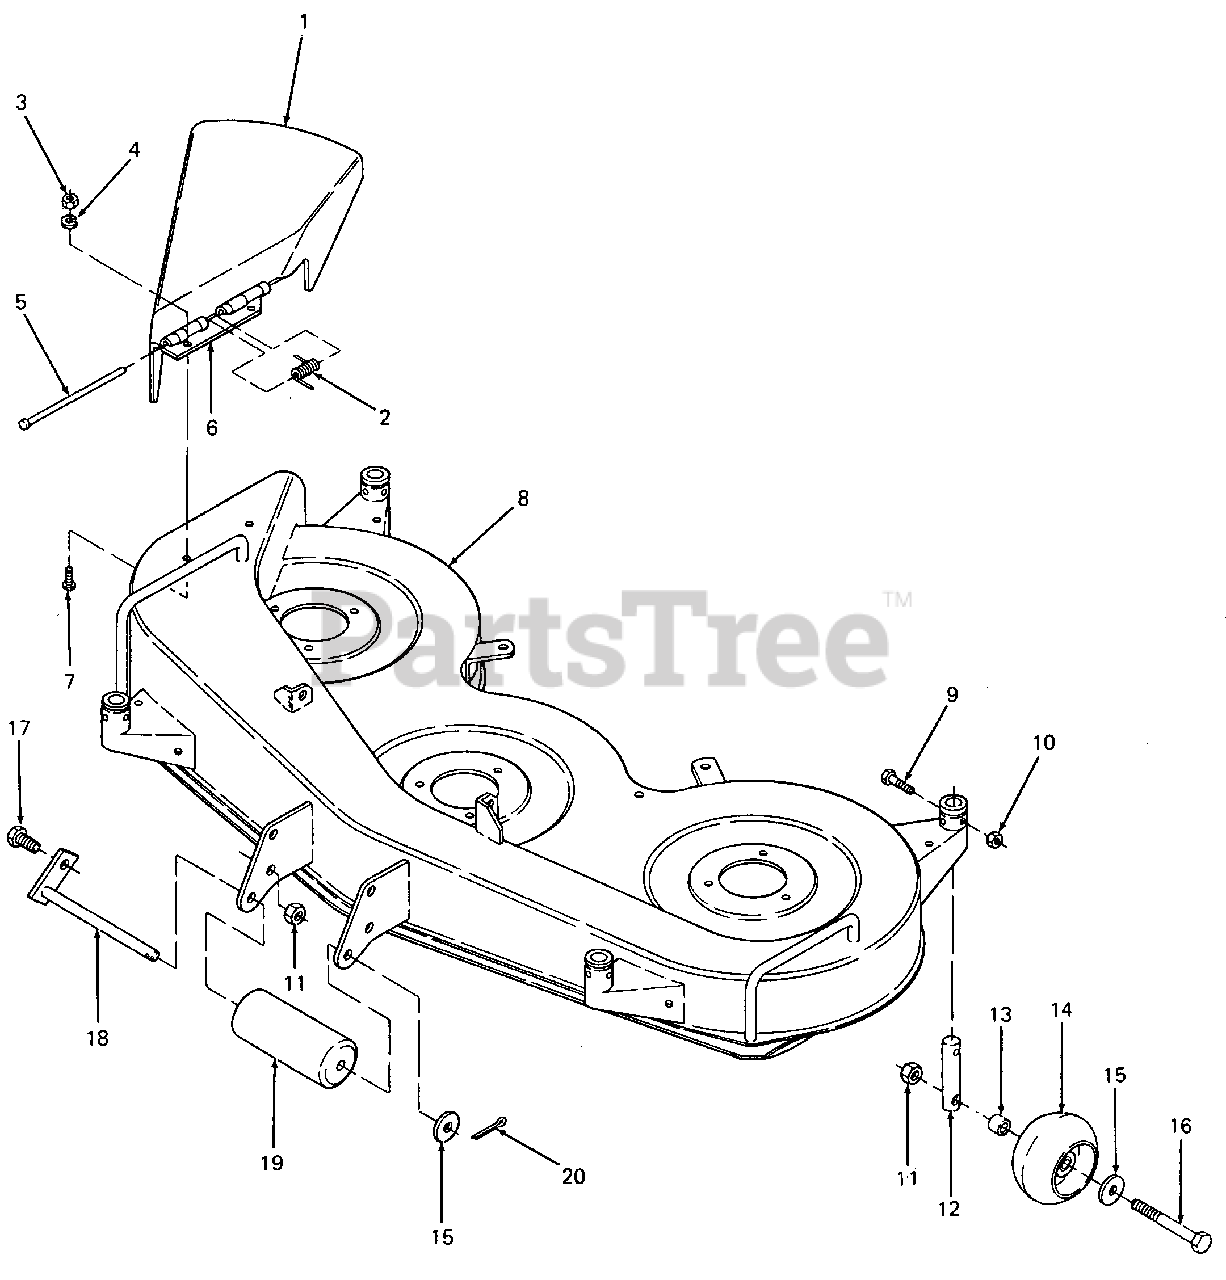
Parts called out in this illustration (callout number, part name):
1	Chute, Discharge w/Graphic
2	Spring, Torsion, .29 ID X 1.14 Lg
3	Nut, Hex Jam, 1/4-20
4	Washer, Lock, 1/4
5	Pin, Hinge, .25 Dia X 6.75 Lg
6	Hinge, Discharge Chute
7	Screw, Truss Mach, 1/4-20 X .75 Lg
8	Deck Assy w/Graphics
9	Screw, Hex Cap, 5/16-18 X 1.5 Lg
10	Nut, Hex Center Lock, 5/16-18
11	Nut, Hex Center Lock, 1/2-13
12	Pin, Gage Wheel
13	Spacer, Gage Wheel
14	Wheel, Ball, 5" Dia
15	Washer, Flat, .531 X 1.25 X .100 Thk
16	Screw, Hex Cap, 1/2-13 X 5.0 Lg
17	Screw, Hex Cap, 1/2-13 X 1.0 Lg GR5
18	Pin, Roller
19	Roller, Front
20	Pin, Cotter, 1/8 Dia X 1.25 Lg
